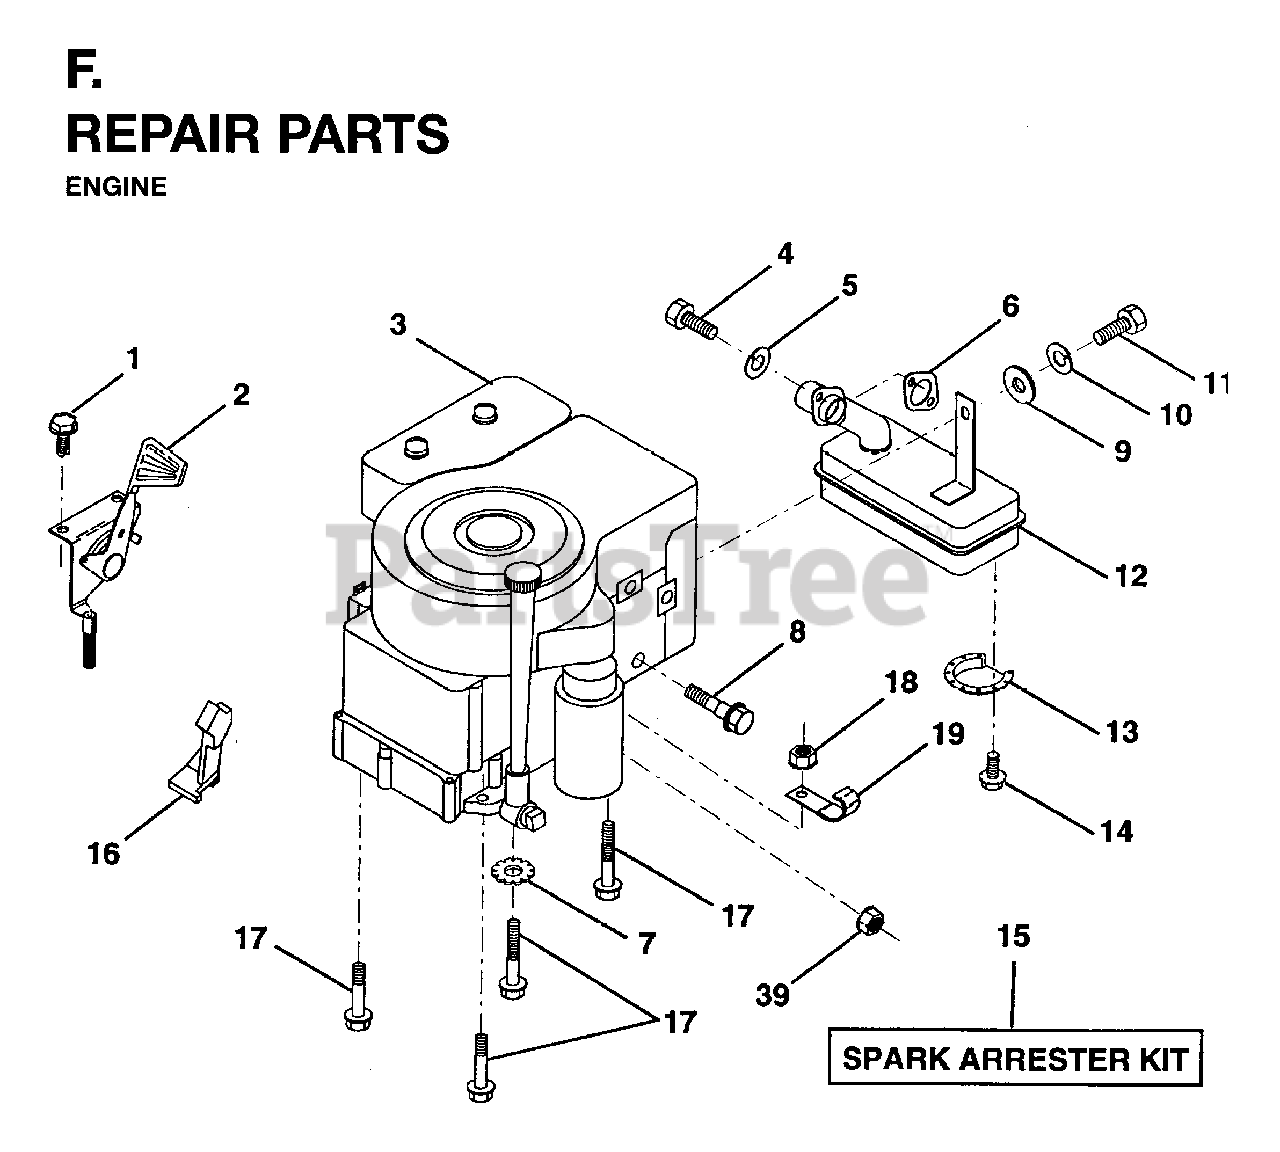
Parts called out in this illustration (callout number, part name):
2	THROTTLE CONTROL
4	SCREW
5	LOCKWASHER
6	GASKET ENG
7	WASHER, LOCK 3/8
9	WASHER - 26X6.5X1.6
10	LOCKWASHER
13	DEFL MUFFLER LTV
14	SCREW
15	ARRESTER SPARK (OPTIONAL)
16	STOP THROTTLE
17	BOLT
18	NUT.HEX.3/8-16UNC
19	CLIP T
39	NUT FLANGE 1/4-20 STARTER NUT
